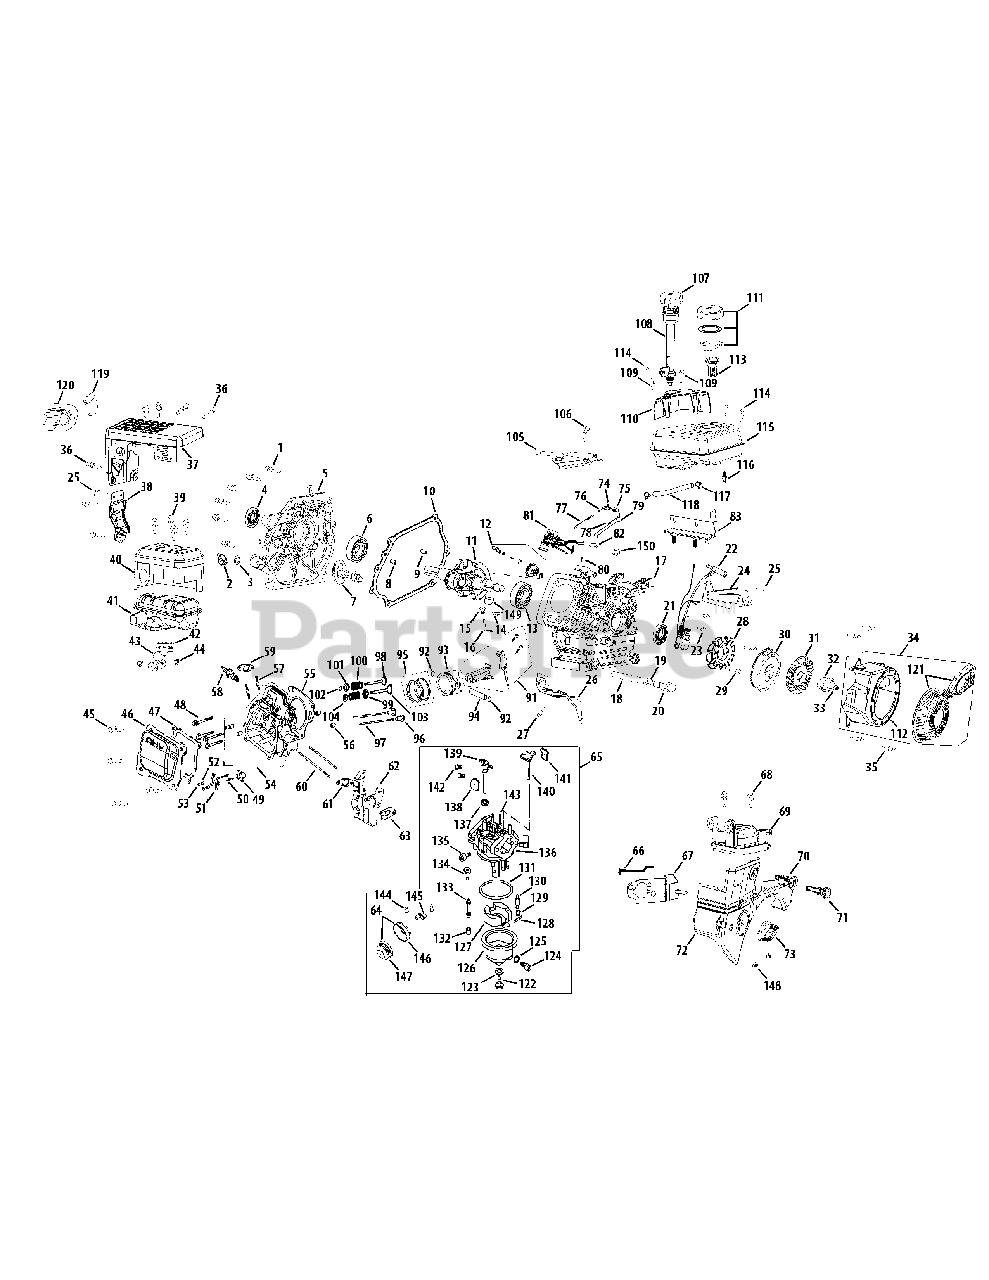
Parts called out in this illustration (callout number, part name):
1	Bolt
2	Oil Fill Plug Assembly
3	O-ring
4	Oil seal, 25 × 41.25 × 6
5	Crankcase cover
6	Radial Ball Bearing
7	Camshaft Assembly
8	Dowel Pin, 9 × 14
9	Dowel Pin, 7 × 14
10	Crankcase Cover Gasket
11	Crankshaft Complete
12	Governor Kit
13	Radial Ball Bearing
14	Pin Lock
15	O-ring, 5.2 × 1.9
16	Governor Arm
17	Crankcase
18	Oil-Draining Pipe
18	Oil Drain Assembly
19	Washer, 10 × 16 × 1.5
20	Drain Bolt, 10 × 1.25
21	Oil Seal, 25 × 41.25 × 6
22	Ignition Module
28	Stator
30	Flywheel
31	Cooling Fan
32	Starter Cup
35	Recoil Bolt
37	Muffler Shroud
40	Muffler Shield
41	Muffler Complete
42	Gasket
47	Valve Cover Gasket
49	Plate Push Rod Guide
50	Pivot Bolt
51	Rocker Arm
52	Valve Adjusting Nut
53	Pivot Locking Nut
54	Cylinder Head Complete
55	Cylinder Head Gasket
56	Dowel Pin, 10 × 16
57	Muffler Stud Assembly, 8 × 34
58	Spark Plug
59	Gasket Muffler
59	Gaske tMuffler
61	Insulator Gasket Carburetor
61	Carburetor Insulator Gasket
62	Insulator Carburetor
62	Carburetor Insulator
63	Carburetor Gasket
63	Gasket Carburetor
65	Carburetor Assembly
66	Choke Push Rod
69	Air Filter Heating Pipe Cover
70	Key Switch
71	Key
72	Shroud
73	Choke Knob
77	Spring Governor
78	Spring Throttle Return
79	Rod Governor
81	Throttle Control Assembly
82	Throttle Control Knob
84	Electric Starter, 110v
91	Connecting Rod Assembly
92	Piston Pin Clip
93	Piston
94	Pin Piston
97	Push Rod
97	Push Rod Kit
98	Exhaust Valve
98	Valve Kit
99	Valve Seal
100	Spring Valve
101	Exhaust Valve Spring Retainer
102	Exhaust Valve Adjuster
103	Intake Valve
104	Internal Valve Spring Retainer
107	Dipstick
108	Dipstick Base
110	Dipstick Decoration Cover
111	Fuel Tank Cap
112	Blower Housing
113	Fuel Filter
115	Fuel Tank
116	Nipple Fuel Tank
117	Fuel Line Kit
121	Recoil Starter Assembly
121	Starter Handle
122	Fuel Drain Plug
123	Fuel Cup Fixed Bolt Packing
124	Fuel Drain Plug
125	Fuel Drain Plug Gasket
126	Fuel Cup
127	Float
128	Floating Pin
129	Needle Valve Spring
130	Needle Valve
131	O-ring Packing
132	Main Jet
133	Main Nozzle
134	Idle Jet Assembly
135	Idle Speed Adjusting Screw
136	Carburetor Body
137	Fiber Seal
138	Choke Plate
139	Throttle Shaft
140	Choke Plate
141	Choke Shaft
142	Cross Screw
143	Position Spring
144	Clip
145	Fuel Hose
146	Primer Base
147	Primer Bulb
147	Primer
149	Woodruff Key
